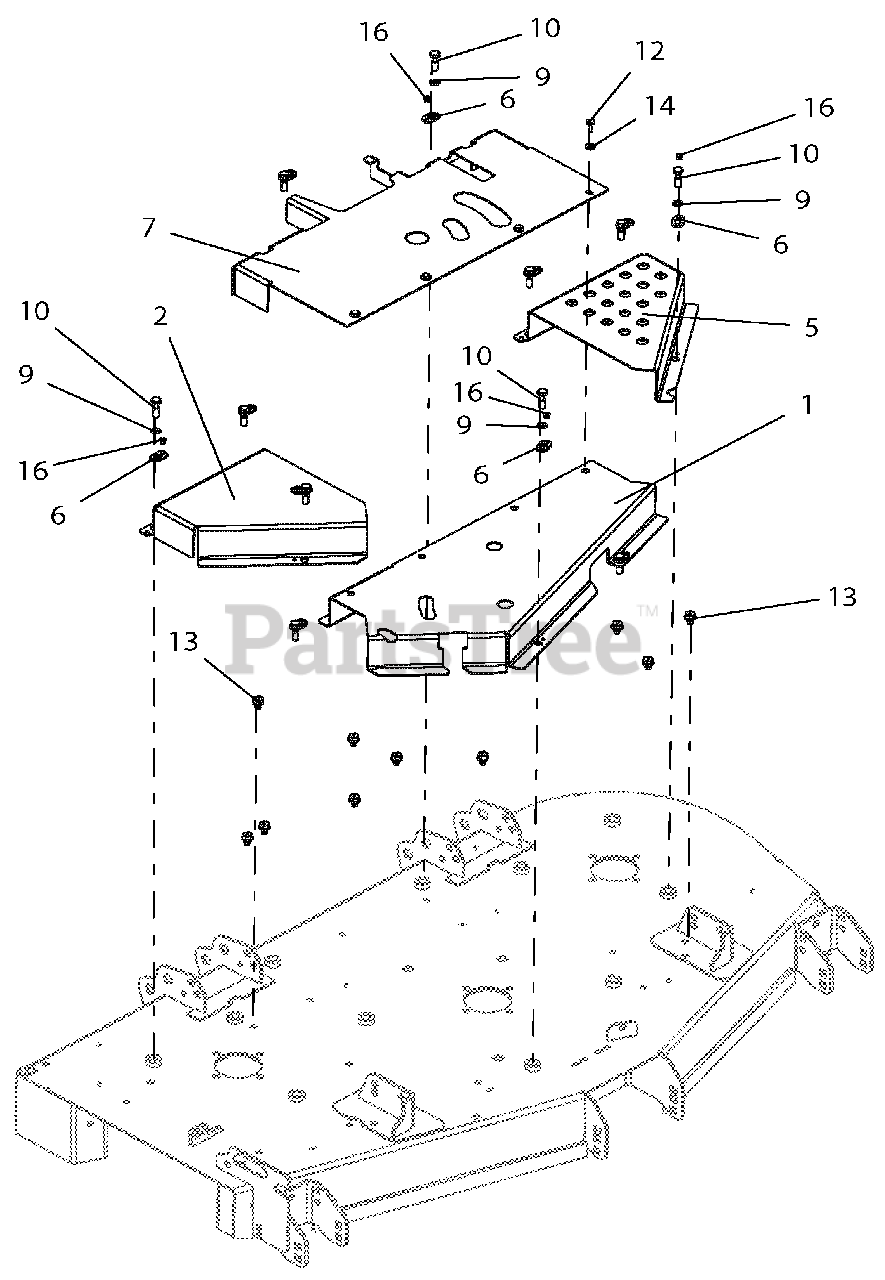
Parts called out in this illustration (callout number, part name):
1	WLDMT, FRONT BELT SHIELD
2	GUARD, RH PT200 CE BELT (BLACK)
5	GUARD, LH PT200 CE BELT (BLACK)
6	KEEPER, BOLT
7	BRKT, REAR BELT GUARD CE-52 (BLACK)
9	LOCK, WSHR-EXT 0.391 X 0.628 X 0.036 YWZC
10	BLT, HEX 0.38-16 X 1.25 GR5 CAPTIVE
12	BLT-HEX .25-20X.75 GR5 YWZC
13	SCR-TAP .38-16X.50 HWH TR YWZ
14	WSHR-FL-STL.281X.62X.065 YWZC
16	RVT-POP .187x.250 (#64) YWZC
